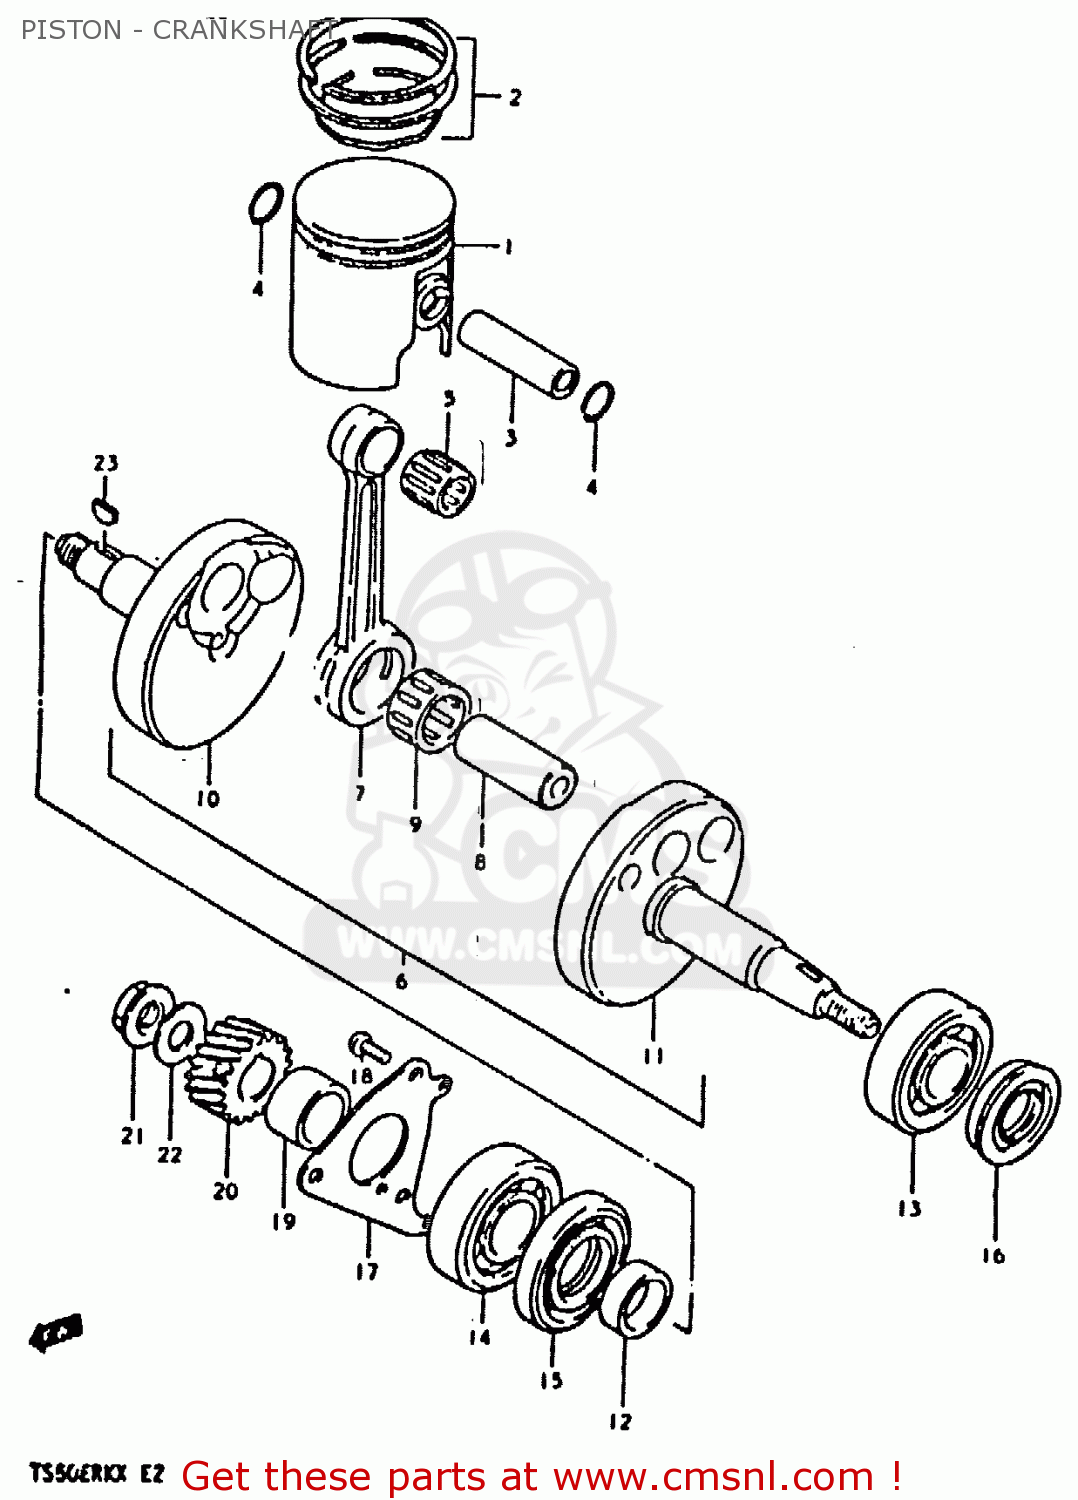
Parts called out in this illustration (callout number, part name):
1	PISTON
2	RING SET,PISTON
3	PIN,PISTON
4	RING,SNAP
5	BEARING
6	CRANKSHAFT ASSEMBLY
7	CONNECTING ROD
8	PIN,CRANK
9	BEARING
10	CRANKSHAFT,RIGHT
11	CRANKSHAFT,LEFT
12	SPACER(20X26X9)
13	BEARING
14	BEARING
15	OIL SEAL
16	SEAL,OIL(19.6X37X8)
17	RETAINER,CRANKSHAFT BEARING,R
18	SCREW 6X12
19	SPACER(20X26X14)
20	GEAR,PRIMARY DRIVE NO.19
21	NUT
22	WASHER
23	KEY
